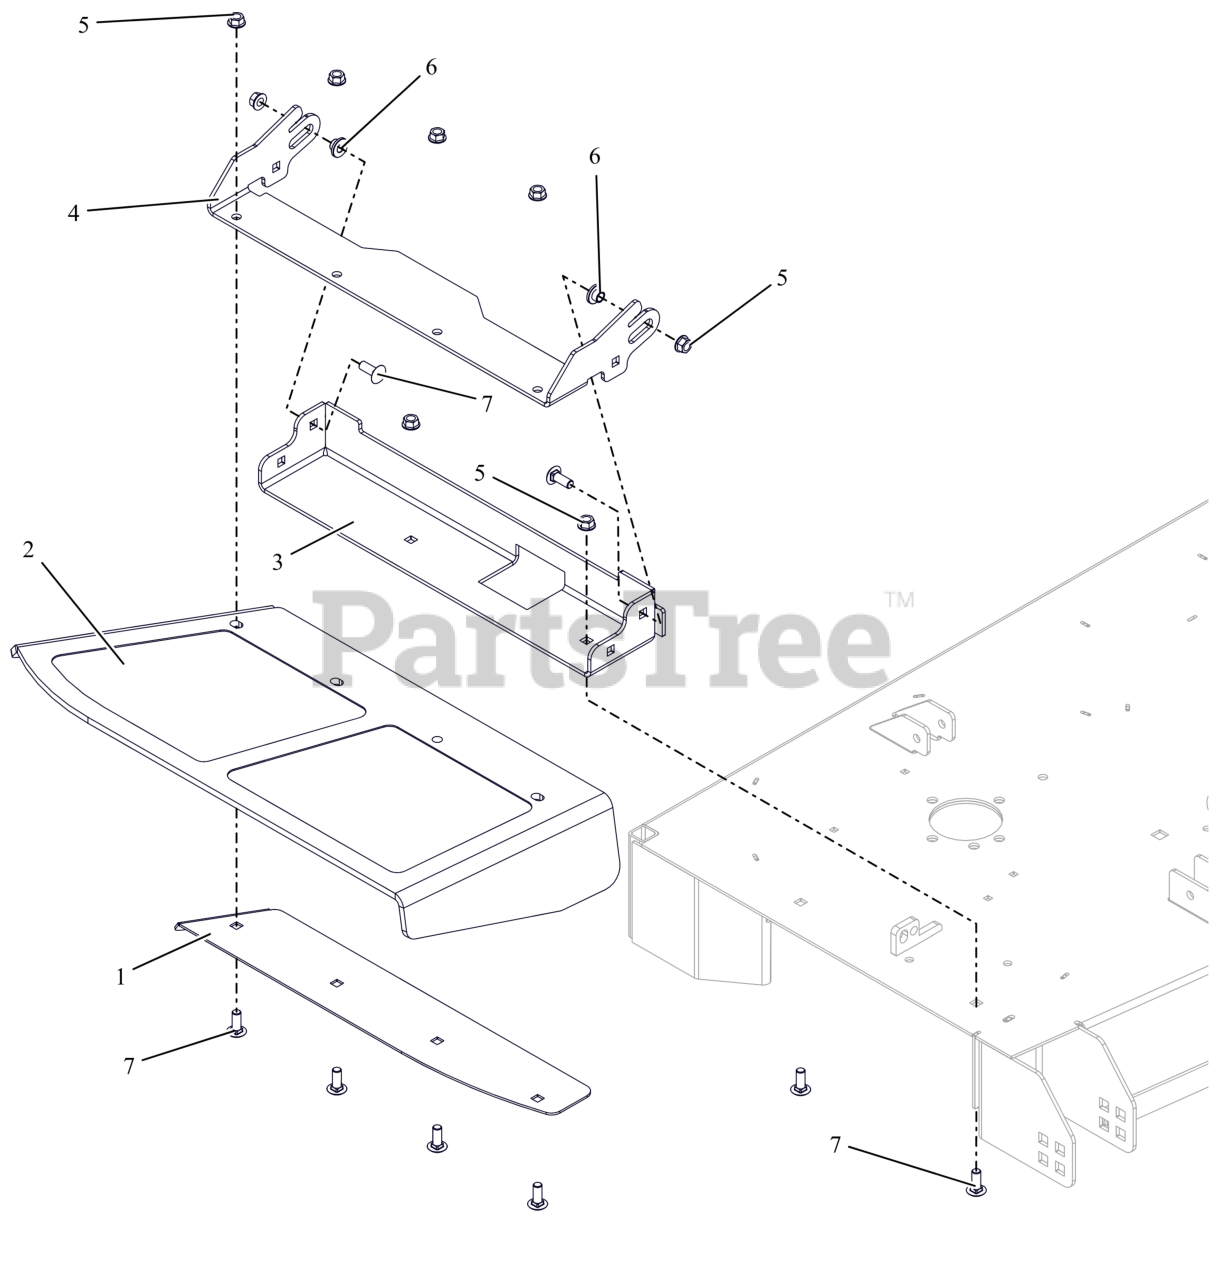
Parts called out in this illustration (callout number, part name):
1	72" DISCH CHUTE CLAMP PLT -RED
2	CHUTE, 72" FORMED RUBBER DISCH
3	BASE, DISCHARGE CHUTE MTG (RED) W/ SAFETY DECALS
4	BRKT, CHUTE MTG (RED)
5	NUT-LK-CTR-FLG .375-16 GF ZCC
6	BSHG-FLG .385X.500X.875X.406
7	BLT,RHSSN .38-16X1.00 G5 ZCC
